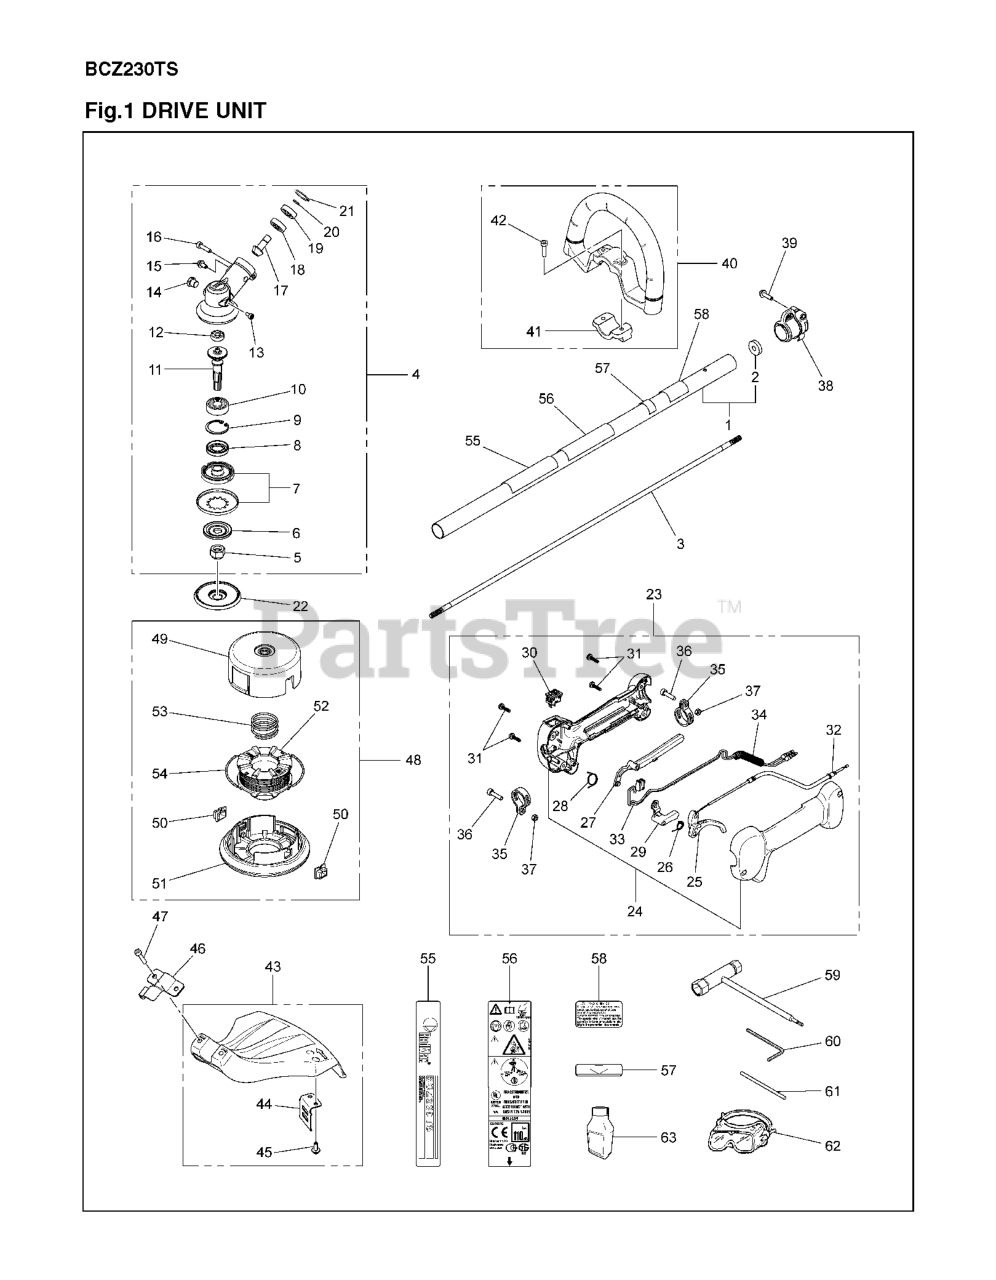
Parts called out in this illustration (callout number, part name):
1	TUBE
3	DRIVESHAFT 525L
4	BEVEL GEAR ASSY
5	GEARHEAD NUT - BRUSHCUTTER
6	SUPPORT FLANGE
7	DRIVER ASSY
10	BEARING***
11	GEAR ASSY
12	BEARING (RPLS T330013520)
14	SCREW M10X1.25 T27
15	BOLT (RPLS T495051010-11)
16	BOLT M5X20 T27
17	PINION HIGH REDUCTION RATIO
23	ASSY THROTTLE
24	GRIP HALF SET
25	LEVER, THROTTLE
26	SPRING, THROTTLE
27	LEVER, SAFETY
29	LEVER JOINT
30	STOP SWITCH NM_09091801
33	CORD - C
37	NUT
38	HANGER COMP.
40	HANDLE LOOP
41	CLAMP HANDLE
43	RP_GUARD ASSY
47	BOLT, TORX
48	TAP HEAD RPLS T318915100/02
49	CASE (RPL T318915112)
51	COVER (RPLS T318915131)
52	HOLDER, CORD (RPLS T318915141)
54	CORD
55	DECAL MODEL
56	DECAL WARNING
58	DECAL SPARK ARRESTOR WARNING
59	COMBINATION WRENCH TORX
60	L-SPANNER
61	LOCKING PIN
62	GOGGLExxx (RPLS
63	OIL 2 CYCLE ENGINE OIL 2.
